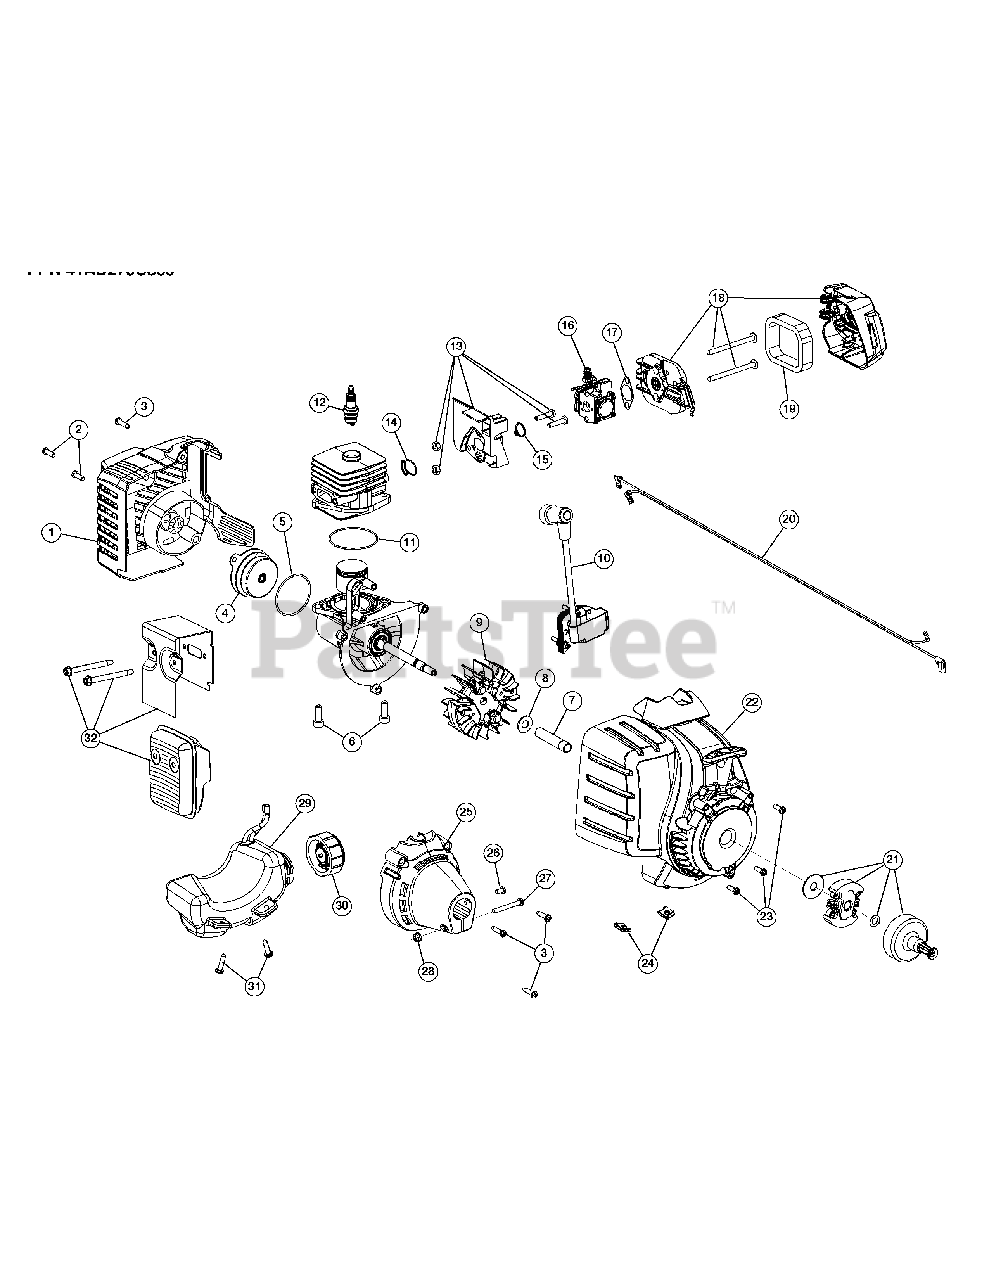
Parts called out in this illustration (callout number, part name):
1	Rear Cover Assembly (Incl. 2 & 3)
2	Rear Housing Screw
3	Cover Screw
4	Electric Starter Cover Assembly
5	O-Ring
6	Crankcase Bolt
7	Spacer
8	Washer
9	Flywheel Assembly
10	Module Assembly
11	Crankcase O-Ring
12	Spark Plug
13	Insulator Assembly (Incl. 14 & 15)
14	Insulator O-Ring
15	Carburetor O-Ring
16	Carburetor
17	Air Cleaner Gasket
18	Aircleaner Cover Assembly (Incl. 19)
19	Aircleaner Filter
20	Lead Wires
21	Clutch Assembly
22	Starter Housing (Incl. 23 & 24)
23	Housing Screw
24	U-shaped Nut
25	Clutch Cover (Incl. 3)
26	Anti-rotation Screw
27	Clamp Screw
28	Clamp Nut
29	Fuel Tank Assembly (Incl. 30 & 31)
30	Fuel Tank Screw
31	Fuel Tank Cap
32	Muffler Assembly
